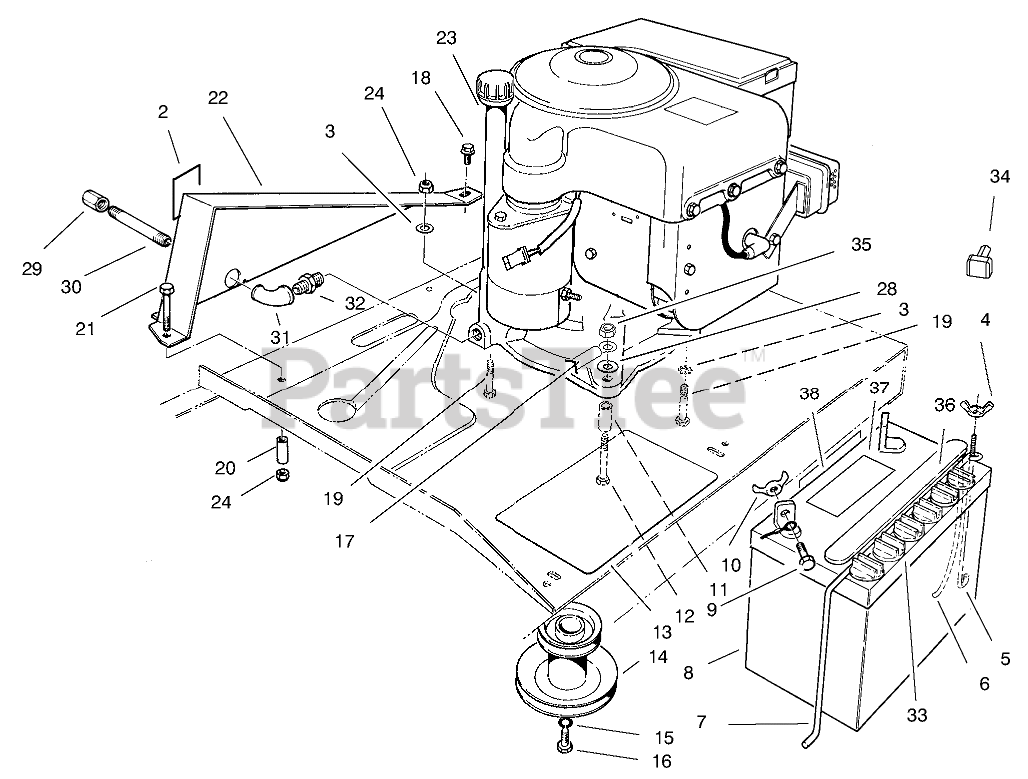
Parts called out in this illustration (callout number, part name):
3	WASHER-PLAIN
4	NUT-WING
5	POST-BATTERY
6	TUBE-BATT DRAIN/80-2600
7	HOLDDOWN-BATTERY
8	Battery
9	SCREW-HH
10	NUT-WING
11	SPACER-PIVOT
12	SCREW-HH
13	PAD-SKID, ANTI
14	PULLEY - ENGINE
15	WASHER-FLAT
16	SCREW-HH
17	ASM - CABLE WIRE
18	SCREW-HWHTF
19	SCREW-HH
20	GUIDE-BELT
21	SCREW-HH
22	GUIDE-CHAIN
23	Engine-8 H.P. B & S
24	NUT-LOCK, NI
28	WASHER-LOCK
29	CAP-PIPE
30	NIPPLE-PIPE
31	ELBOW-STREET
32	BUSHING-PIPE
33	CAP-BATTERY
34	BOOT-TERMINAL
35	NUT-HEX, SIDE DEFORM
36	DECAL - DANGER
37	DECAL-DANGER
38	DECAL-BATTERY
